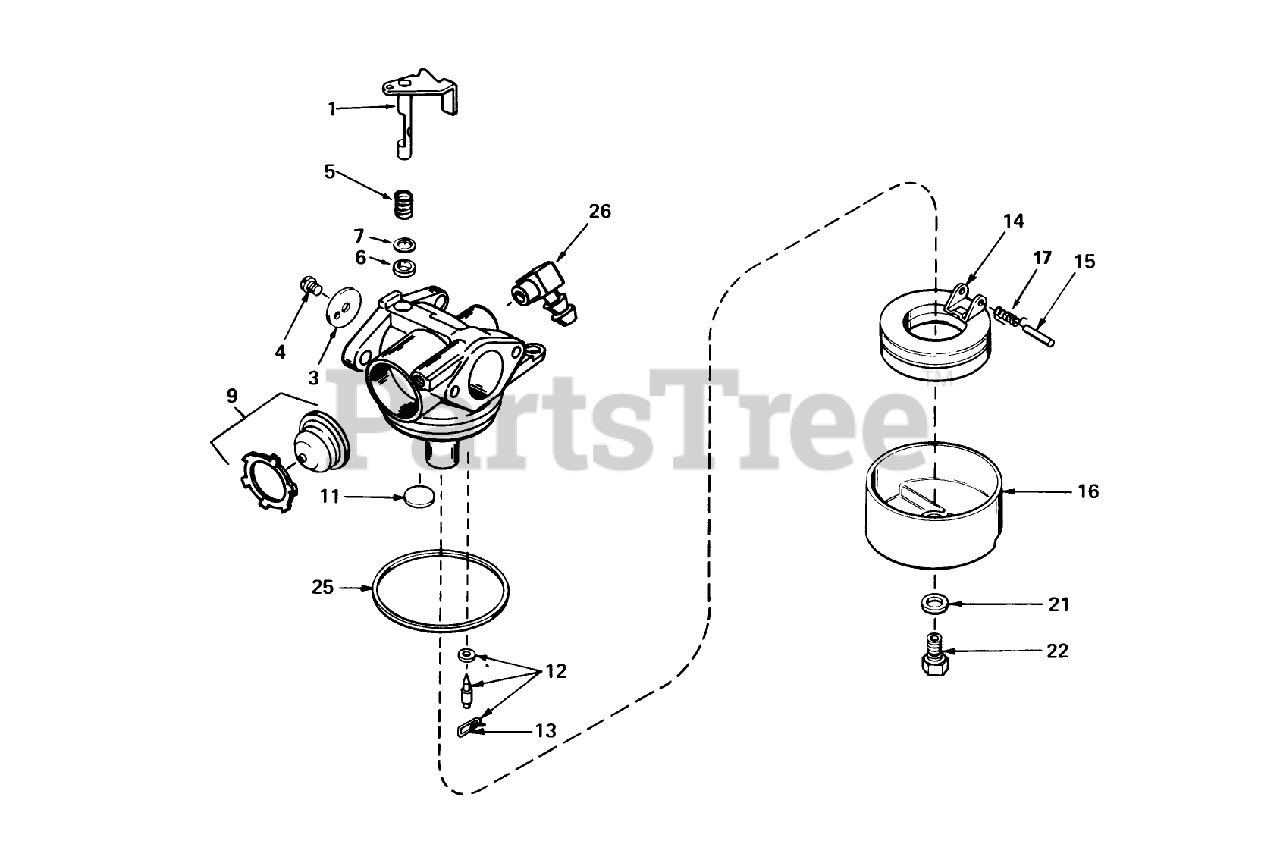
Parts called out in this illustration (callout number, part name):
1	Throttle Shaft Lever Assy.
3	Shutter-Throttle
4	Screw-Shutter
5	Spring-Trottle, Return
6	Seal-Dust
7	Washer-Seal, Dust
9	Bulb-Primer
11	Plug-Welch, Atmospheric Vent
12	Inlet Needle, Seat Clip Assy. (Incl. No. 13)
13	Clip-Spring
14	Float
15	Shaft-Float
16	Bowl-Float (no drain)
17	Spring-Float, Dampening
21	Washer-Bowl Nut
22	Nut-Float Bowl
25	O Ring-Bowl, Float
26	Fitting-Fuel
